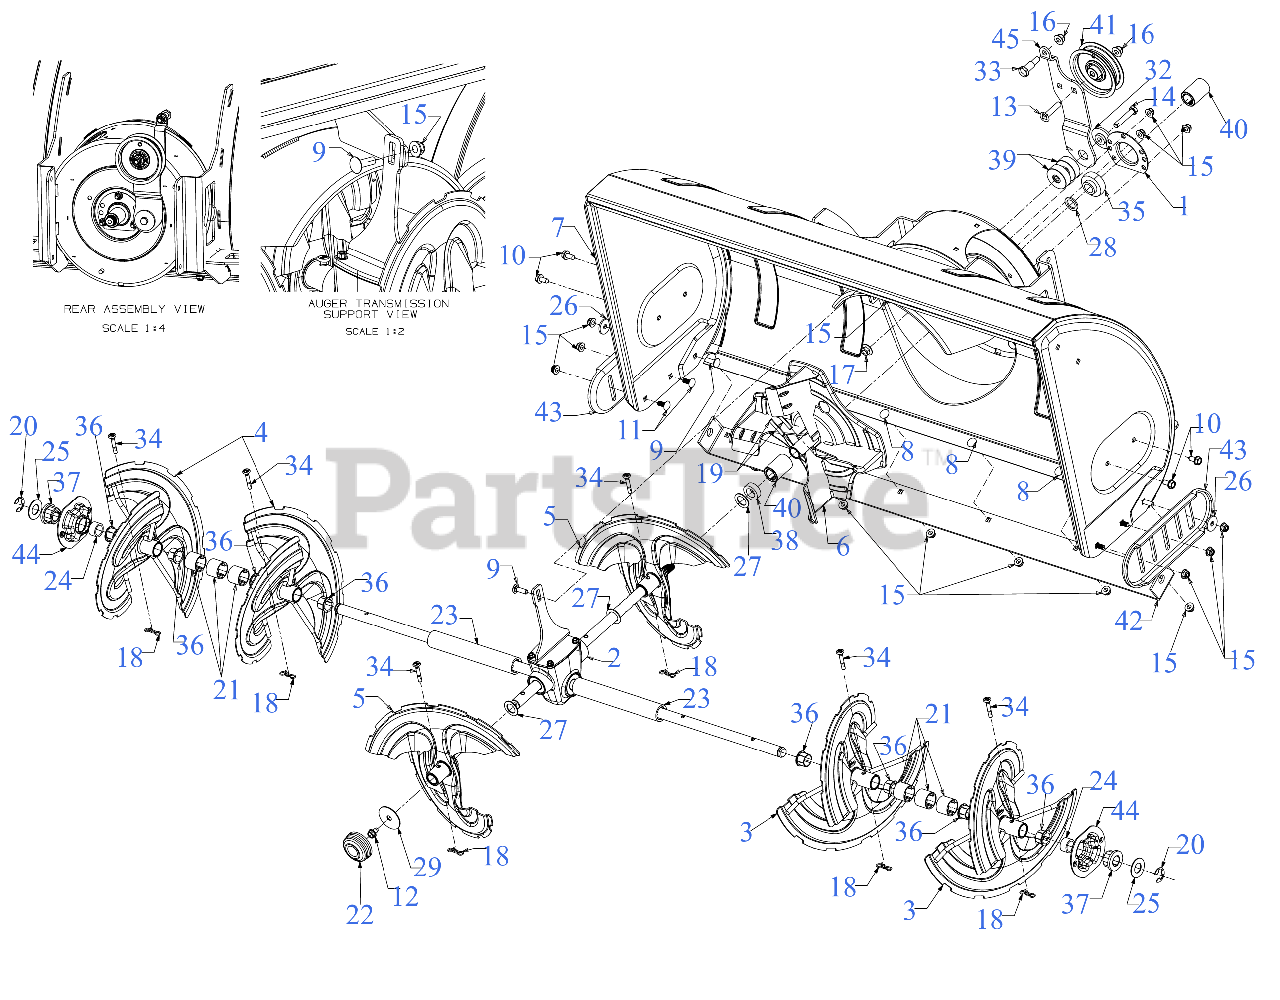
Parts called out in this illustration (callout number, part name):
1	HOUSING-BEARING
2	42" AUGER GEARBOX ASSEMBLY
6	IMPELLER ASSEMBLY (POWDER BLACK)
8	CARRIAGE BOLT 5/16-18 x .62 GR5
9	CARRIAGE BOLT 5/16-18 x 1.00
10	SCREW 5/16-18 x .750
11	CARRIAGE BOLT 5/16-18 x .75
12	SCREW 5/16-18 x .500
13	CARRIAGE BOLT 3/8-16 x 1.75 GR1
14	SCREW 3/8-16 x 2.0 GR5
15	FLANGE LOCK NUT 5/16-18
17	FLANGE LOCK NUT
18	BOW TIE COTTER PIN 1/4-5/16
19	PIN ROLL
20	E-RING
21	SPACER 1.25OD x .75ID X1.00 LG
25	FLAT WASHER .760ID X1.49OD x .06
26	FLAT WASHER
27	FLAT WASHER .793 ID X1.240X.06
28	FLAT WASHER .75 x 1.13 x .10
29	HUB CAP WASHER .406 x 1.92 x .060
32	SHOULDER SPACER
33	SHOULDER BOLT .50X.892X3/8
34	SHEAR PIN (.25 x 1.50)
34	Cub Cadet SHEAR PINS (3X SNOW)
35	BEARING W/OUT COLLAR
36	FLANGE BUSHING
37	FLANGE BEARING
39	SPACER .385ID x 1.75OD x .585THK
41	FLAT PULLEY
42	SHAVE PLATE 42"
43	SLIDE SHOE (POWDER BLACK)
45	IDLER PIVOT BRACKET (POWDER BLACK)
